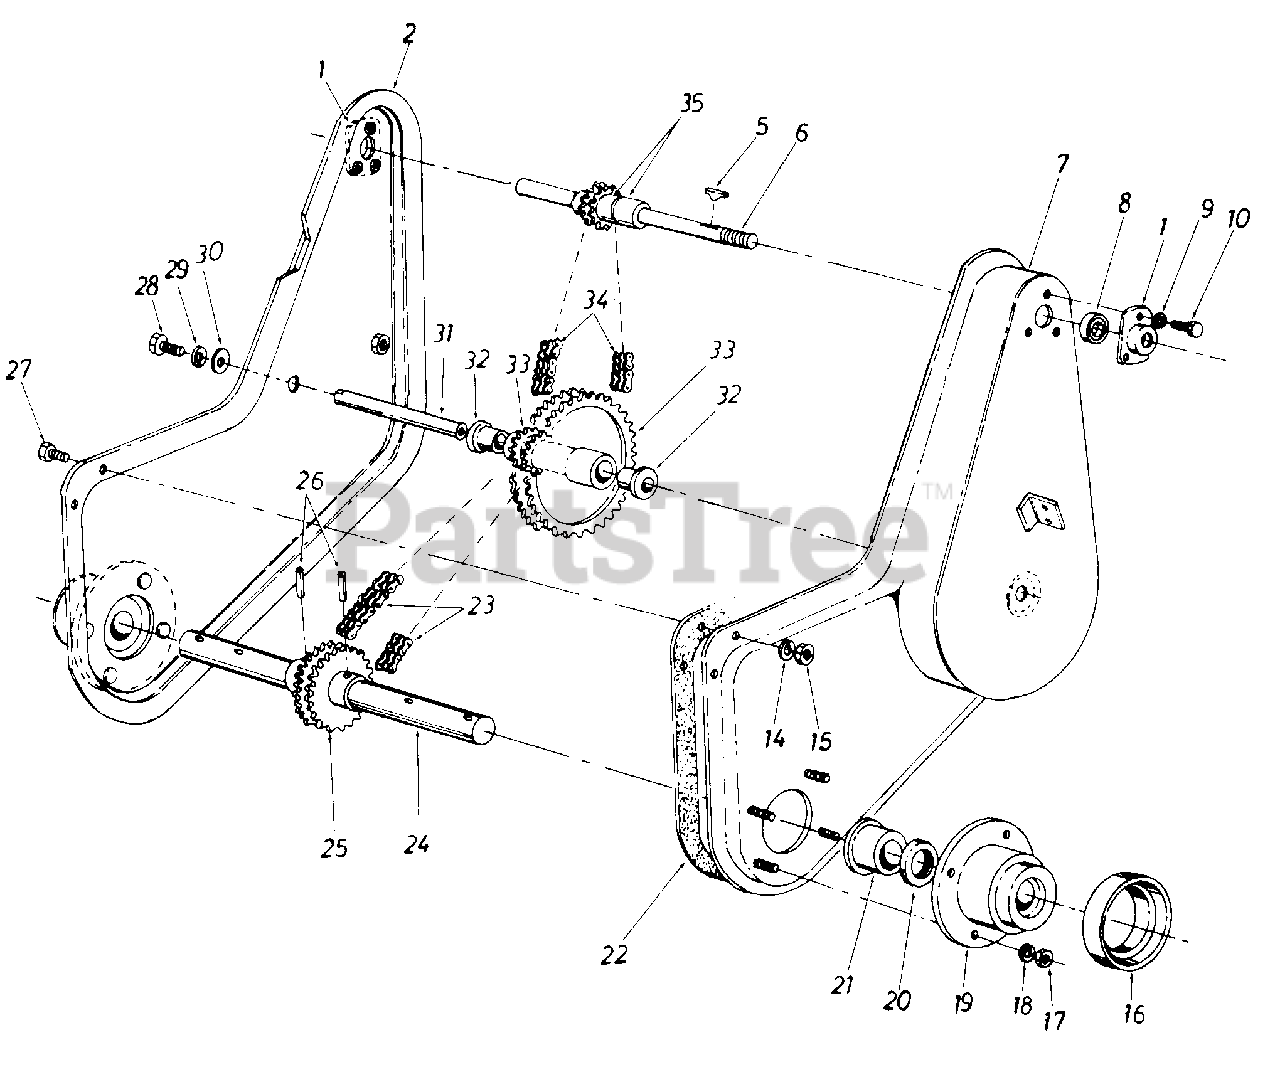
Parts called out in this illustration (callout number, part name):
1	Bearing Housing 1.375" Dia.
2	Housing Assembly R.H.
5	#6 Hi-Pro Key 5/32" x .62" Lg.
6	Input Shaft Assembly
9	L-Wash. 1/4" I.D.*
10	Hex Bolt 1/4-20 x .62" Lg.
14	L-Wash. 1/4" I.D.
15	Hex Cent. L-Nut 1/4-20 Thd.
16	Dust Cap Cover
17	Hex Cent. L-Nut 5/16-18 Thd.
18	L-Wash. 5/16" I.D.
19	Cast Bearing Housing
20	Oil Seal
21	Flange Bearing 1.25" I.D. x 1.75" O.D.
22	Gasket
23	Roller Chain #40-2 x 34.0" Lg.
24	Tine Shaft
25	Double Sprocket T24-2 Teeth 1/2" Pitch
26	Spiral Pin 3/8" Dia. x 2.00" Lg.
27	Hex Bolt 1/4-20 x .62" Lg.*
28	Hex Bolt 5/16-18 x .75" Lg.*
29	L-Wash. 5/16" I.D.*
30	Fl-Wash. 5/16" I.D.
31	Sprocket Shaft
32	Flange Bearing .62" I.D. x .75" O.D.
33	Double Sprocket Assembly
34	Roller Chain #35-2 x 36.75" Lg.
35	Spacer 5/8" I.D. x 7/8" O.D.
